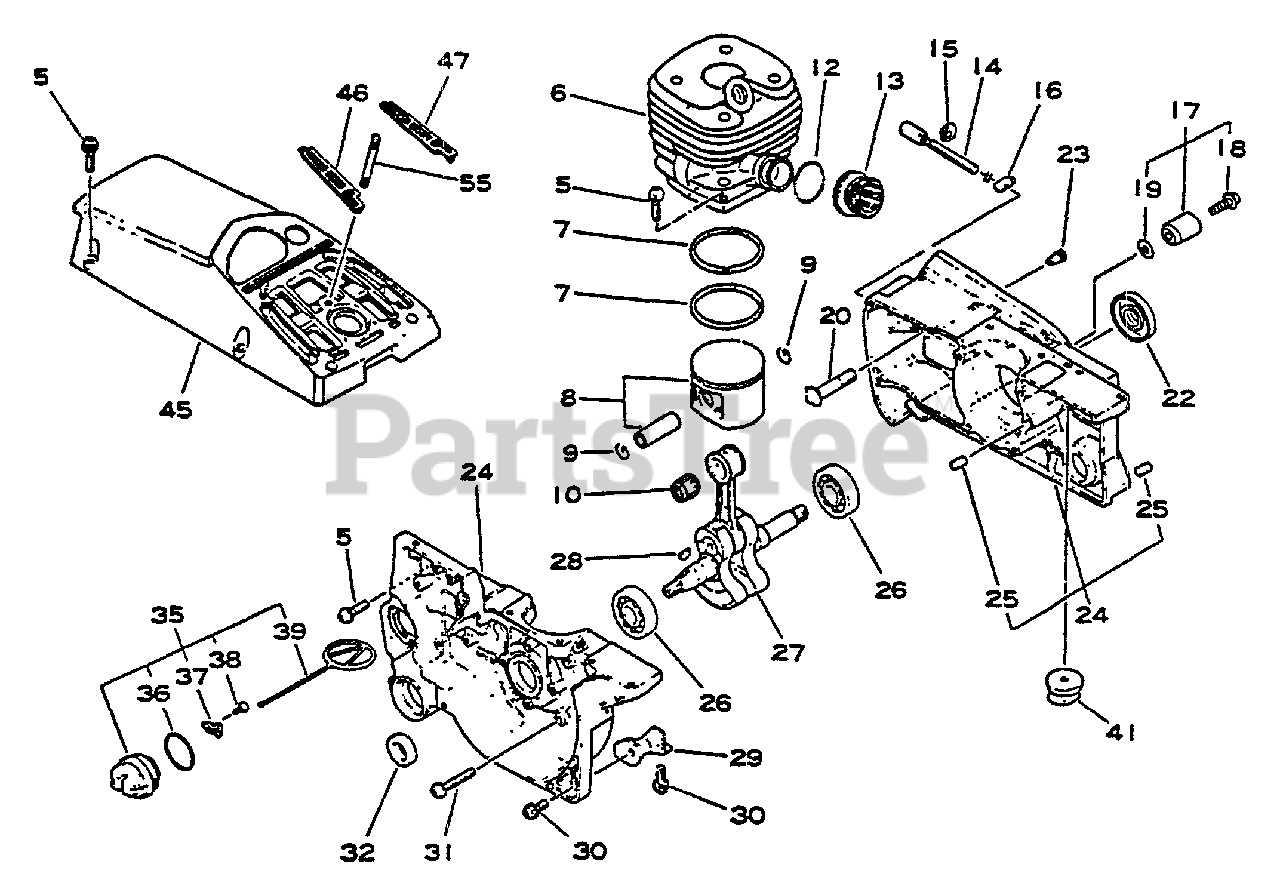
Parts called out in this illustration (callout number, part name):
5	SCREW - 5×20
6	CYLINDER
7	RING, PISTON
8	PISTON KIT
9	RING, SNAP
10	BEARING, NEEDLE
13	ADAPTOR, INTAKE
14	SCREW, ADJUSTER
16	TENSIONER, CHAIN
17	CHAIN CATCHER KIT
18	SCREW - 5×20
19	WASHER, FLAT 5.5×10×0.8
20	STUD, GUIDE BAR 8
21	PIN, SPRING 5×10
22	SEAL, OIL
23	VENT ASSY
24	CRANKCASE KIT
25	PIN, LOCATING 5×10
26	BEARING SET
27	CRANKSHAFT ASSY
28	KEY, WOODRUFF
30	SCREW - 5×14
31	SCREW 5×35
32	SEAL, OIL
35	CAP ASSY
37	RETAINER, CONNECTOR
38	SCREW 3×8
39	CONNECTOR, CAP L= 60 MM
45	COVER, ENGINE
46	FILTER, AIR
47	FILTER, AIR
